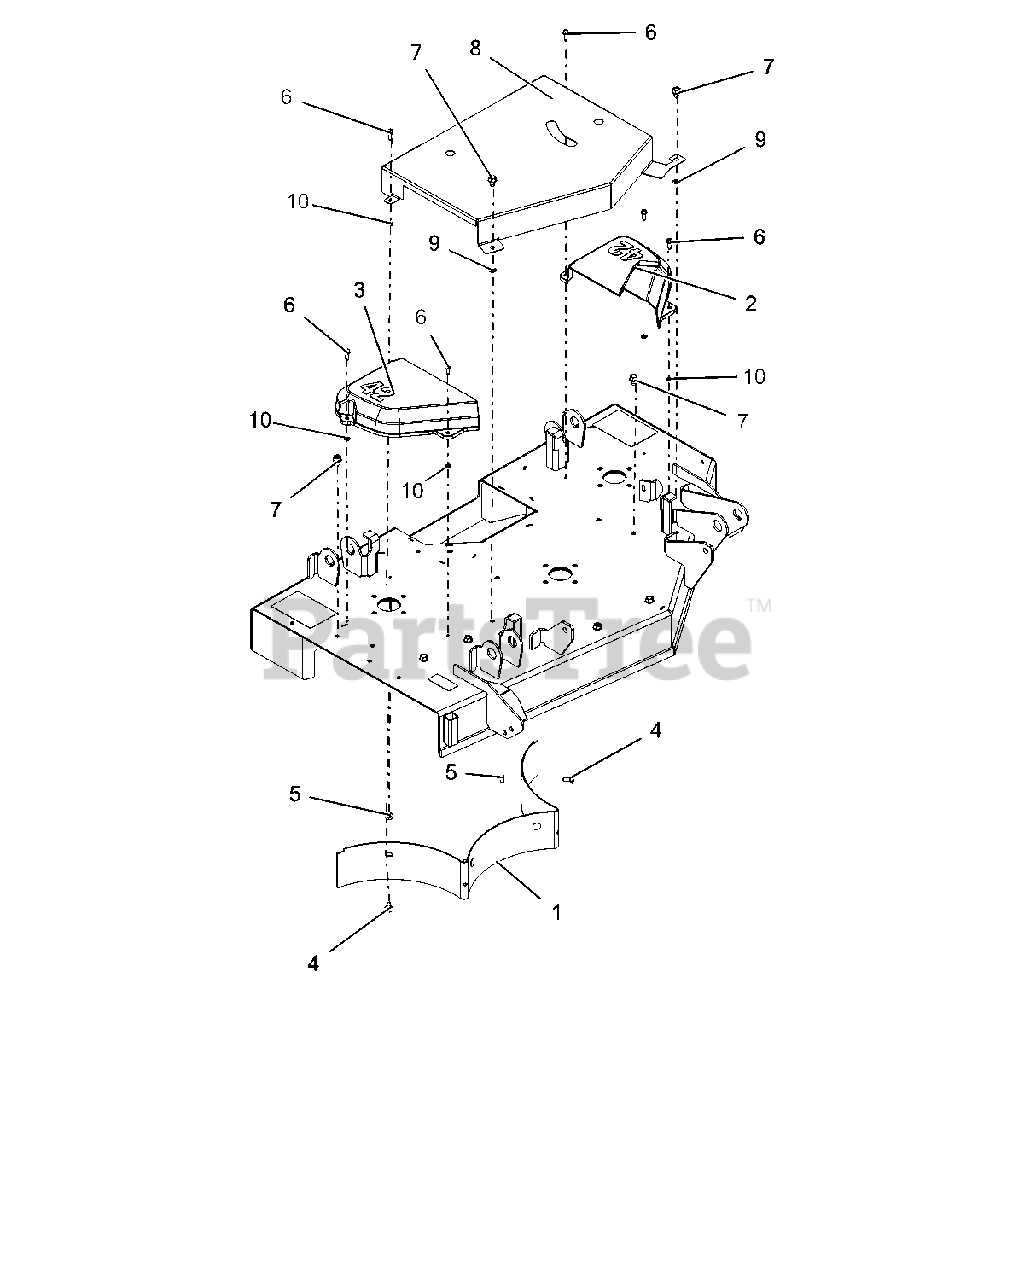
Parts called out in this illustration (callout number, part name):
1	BAFFLE, REAR 42
2	COVER, BELT 42" LH
3	COVER, BELT 42" RH
4	@BLT-RDHDSQNK .31-18X.75 G5YZ
5	@NUT-LK-TOP-FLG .31-18 YWZC
6	SCR-TAP-PM .25-20X.75 TR YWZ
7	@SCR-TAP .38-16X.50 HWH TR YWZ
8	GUARD, IKON BELT - 42" CE
9	NUT-PUSH .312
10	NUT-PUSH .25X.50 O.D.
